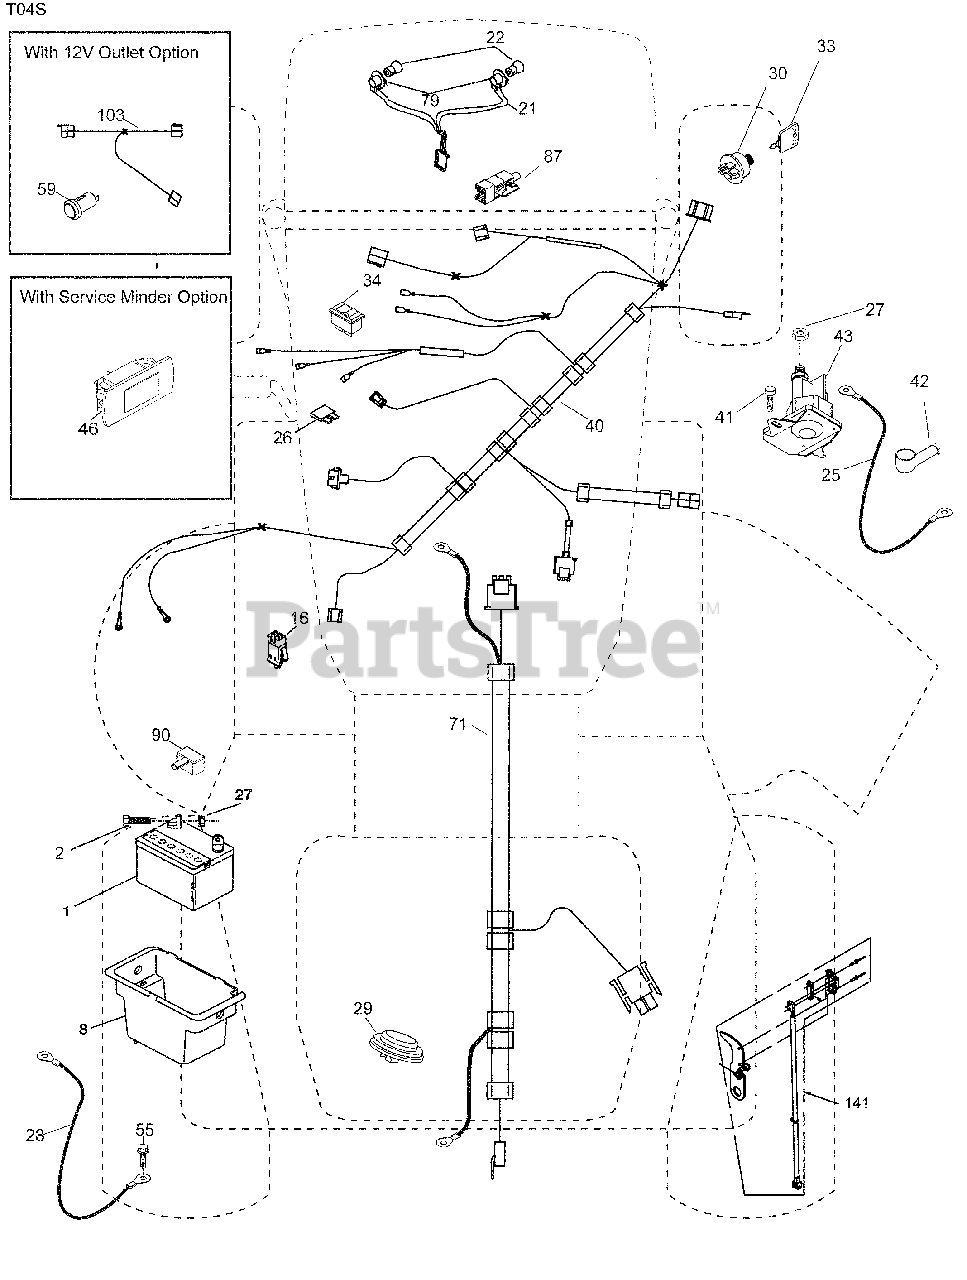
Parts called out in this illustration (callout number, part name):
1	Battery
2	Bolt Hex Head 1/4-20 x 3/4
8	Box Battery
16	Switch Interlock Push-In
21	Harness Socket Light w/4152J
22	Bulb Light
25	Cable Starter
27	Nut Keps Hex 1/4-20 unc
28	Cable, Ground
29	Switch, Seat
30	Switch, Ign
33	Key/Chain
34	Switch Light/Reset
40	Harness Ign. Dash
41	Screw Thd Cut 1/4-20 x 1/2
42	Cover, Terminal
43	Solenoid
46	Gauge Serviceminder Hrmtr
55	Screw Thdrol 5/16-18 x 3/4 TYTT
71	Harness Ign.
79	Socket Asm. Bulb
87	Switch Interlock
90	Cover Terminal
141	Kit GT ROS (71677)
